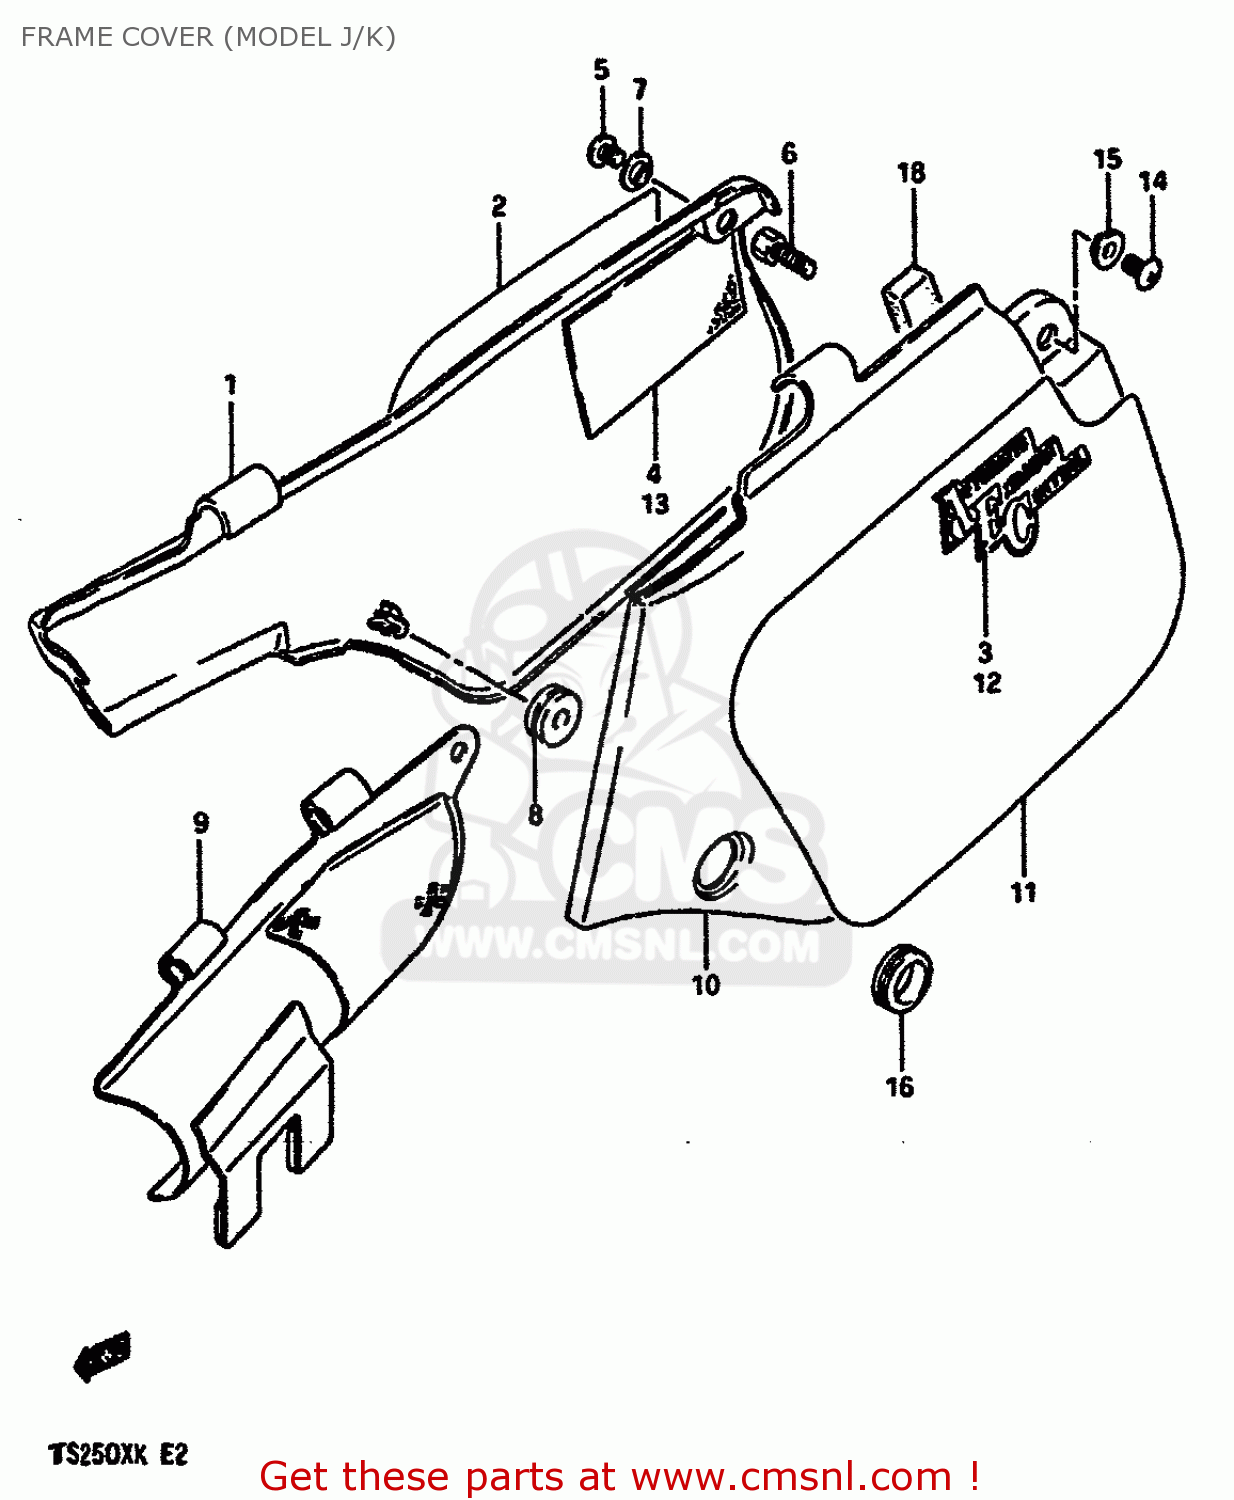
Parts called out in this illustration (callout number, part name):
1	COVER,FRAME RH (YELLOW)
2	TAPE SET,RH (BLUE)
3	EMBLEM
4	HEAT SHIELD,FRAME COVER
5	SCREW 6X12
6	BOLT,SIDE COVER RH INNER
7	WASHER
8	CUSHION
9	PLATE ASSY,GUIDE
10	COVER,FRAME LH (WHITE)
11	TAPE SET,LH (BLUE)
12	EMBLEM
13	PROTECTOR
14	SCREW 6X12
15	COVER,FRAME LH (BLACK)
16	TAPE SET,LH (BLUE)
17	EMBLEM
18	PROTECTOR
19	SCREW 6X12
20	WASHER
21	GROMMET,SEAT LOCK HOLE
